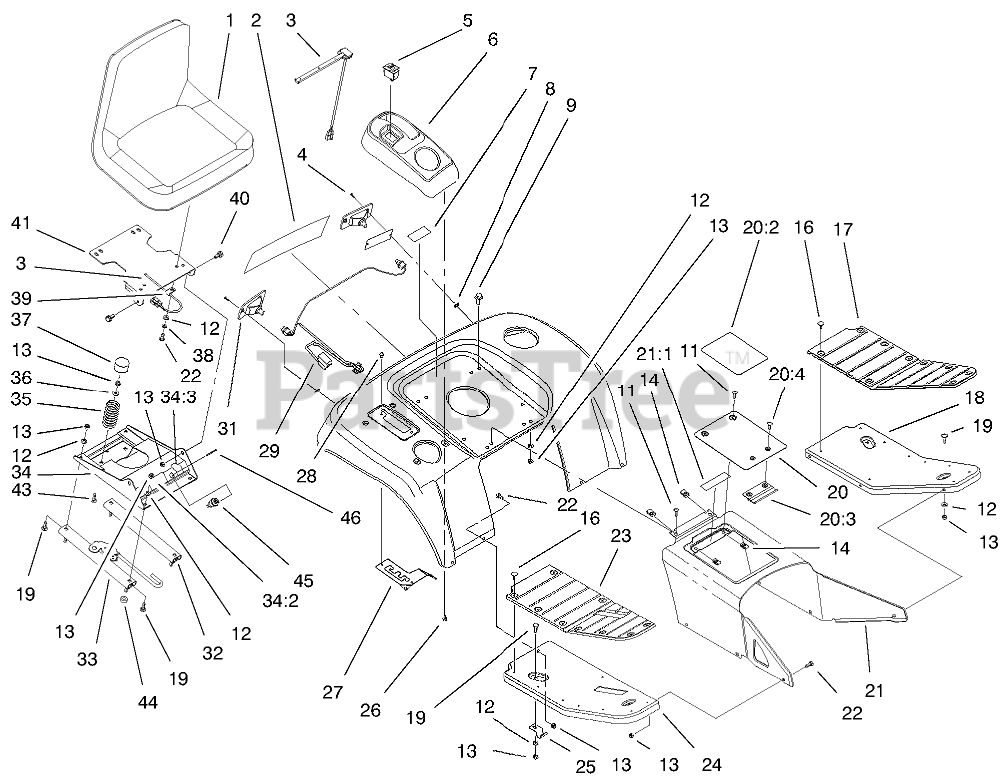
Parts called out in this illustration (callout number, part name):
1	SEAT
2	DECAL - FENDER
3	SWITCH-SEAT
4	SCREW-PPH
5	SWITCH-CRUISE
6	Pod-Control (Only On: 73547)
6	Pod-Control Int-l (Only On: 73580)
7	Decal-USA (Only On: 73547)
8	NUT-SPEED
9	SCREW-HHF
11	SCREW-HH
12	WASHER-PLAIN
13	NUT-LOCK, NI
16	FASTENER-PANEL
17	PAD-FOOTREST, LH
18	FOOTREST-LH
19	SCREW-CARR
20	ASM Cover/Decal (Only On: 73547)
20	ASM-Tunnel Cover Europe (Only On: 73580)
20:2	Decal-Danger (Only On: 73547)
20:2	Decal-Danger Europe (Only On: 73580)
20:3	RETAINER-COVER
20:4	Screw-Plastite (Only On: 73547)
20:4	Screw-Pan Hd (Only On: 73580)
21	ASM-Tunnel w/Decal Europe (Only On: 73580)
21	ASM-Tunnel w/Decal (Only On: 73547)
21:1	Decal-Danger (Only On: 73547)
21:1	Decal-Warning (Only On: 73580)
22	SCREW-HH
23	PAD-FOOTREST, RH
24	FOOTREST-RH
25	BRACKET-FOOTREST
26	SCREW-HHFTF
27	GATE-HI / LO SHIFT
28	SCREW-HWH
29	HARNESS-REAR
31	LAMP-TAILLIGHT
32	SLIDE-SLAVE, SEAT
33	SLIDE-LATCH, SEAT
34	Seat Base ASM (Only On: 73547)
34	Seat Base ASM-Intl (Only On: 73580)
34:2	Decal-Danger (Only On: 73547)
34:3	Decal-Nmir Switch (Only On: 73547)
35	SPRING-COMPRESSION
36	BUSHING
37	CAP-SPRING, SEAT
38	WASHER-LOCK
39	CLAMP-R
40	BOLT-SHOULDER
41	Mount-Seat
43	SCREW-CARR
44	WASHER-FLAT
45	STARTER SWITCH ASM
46	KEY-IGNITION
